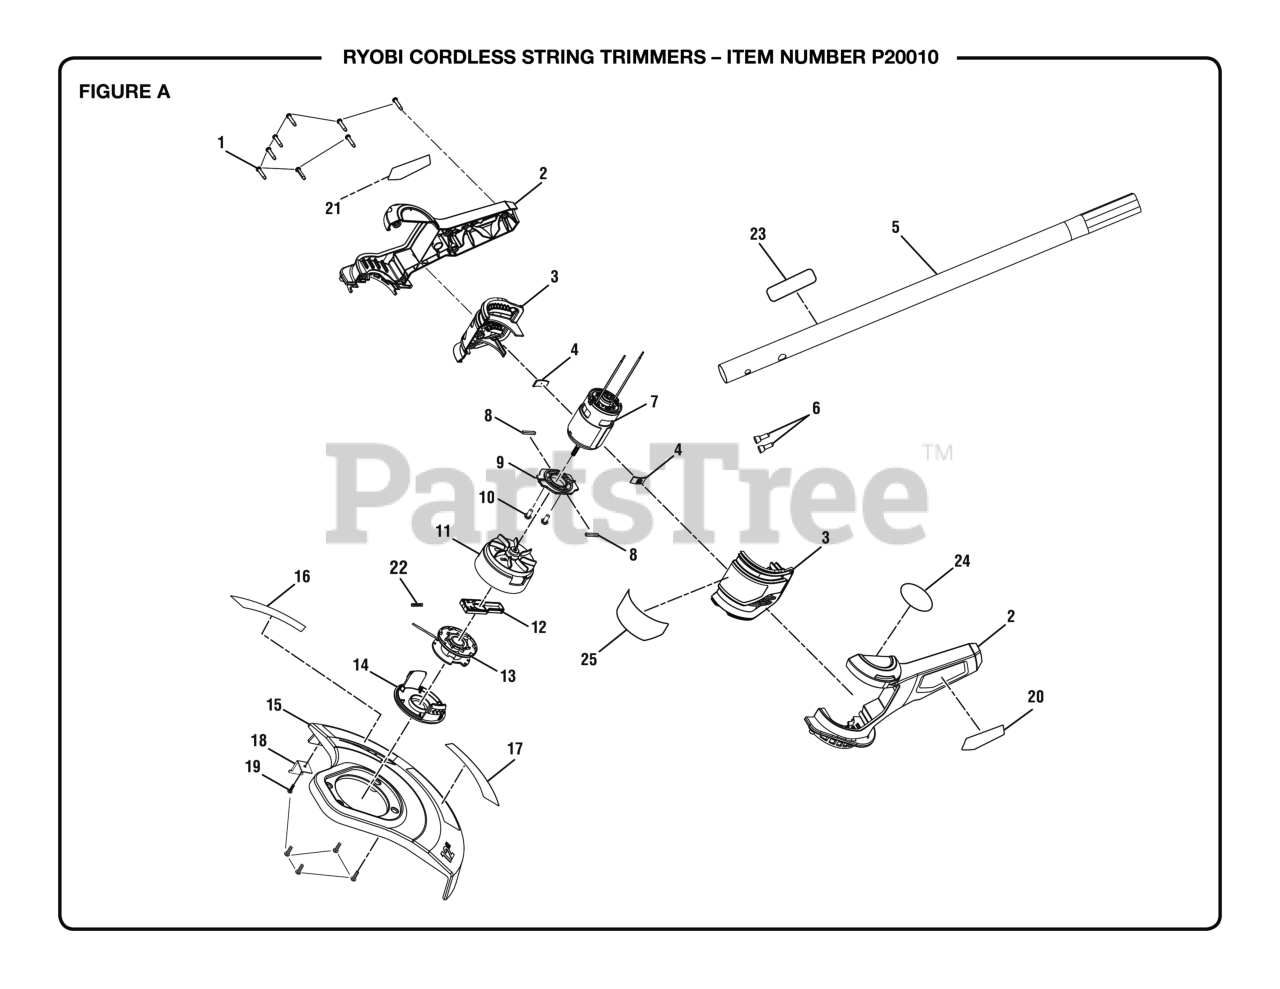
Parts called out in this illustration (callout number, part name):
1	Screw (M4 x 18 mm, T15 Torx Pan Hd.)
2	Motor Housing Assembly
3	Lower Housing Assembly
4	Rubber Plate (Motor)
5	Lower Tube Assembly
6	Wire Connector (Closed End)
8	Rubber Plate (Motor Plate)
9	Motor Mounting Plate
10	Screw w/Lock Washer (M5 x 8 mm, Pan Hd.)
11	Spool Base w/Fan
12	Slider Assembly
13	Spool w/Line Assembly
14	Spool Cap
15	Guard Assembly
16	Adjustable Cutting Width Label
17	Autofeed String Head Label
18	Line Cut-Off Blade
19	Screw (M4 x 12 mm, Pan Hd.)
20	Left Side Motor Label
21	Right Side Motor Label
22	Compression Spring (Internal Tooth)
23	Lower Boom Lithium Label
24	"R" Badge Label
25	Front Motor Label
